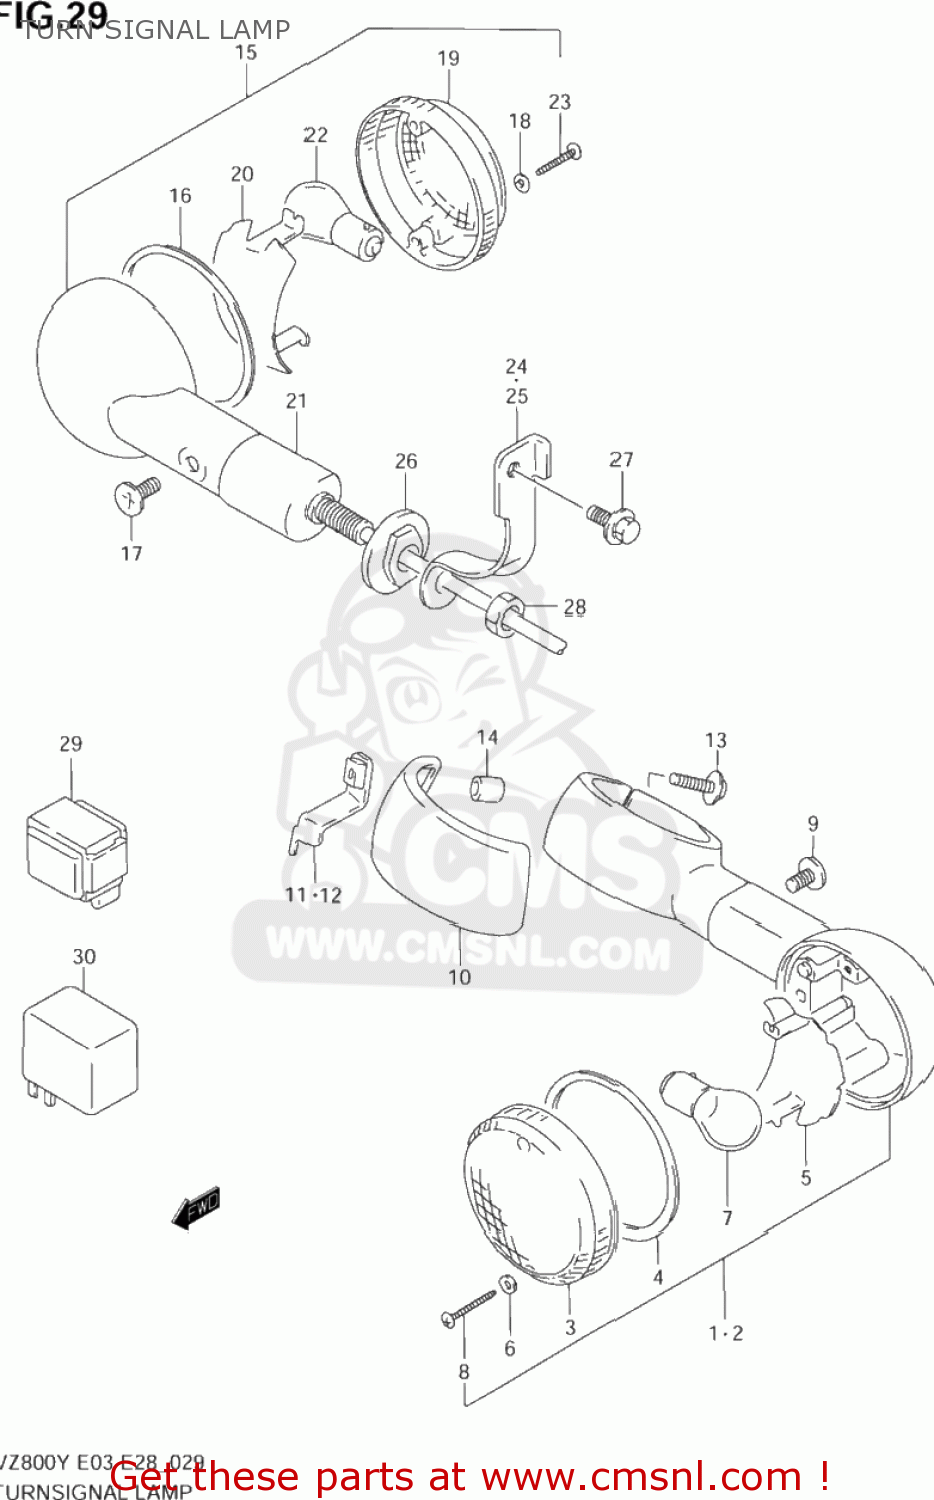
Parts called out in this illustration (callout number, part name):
1	LAMP ASSY,FR TURN SIGNAL,R
2	LAMP ASSY,FR TURN SIGNAL,L
3	LENS
4	GASKET (NAS)
5	REFLECTOR
6	GASKET (NAS)
7	BULB(12V21/5W)
8	SCREW
9	SCREW
10	COVER,FR TURNSIGNAL STAY
11	BRACKET,FR TURNSIGNAL,R
12	BRACKET,FR TURNSIGNAL,L
13	SCREW(6X25)
14	SPACER(6.4X9.2X12)
15	LAMP ASSY,RR TURNSIGNAL,R
16	GASKET (NAS)
17	SCREW
18	GASKET (NAS)
19	LENS
20	REFLECTOR
21	STAY,TURNSIGNAL RR
22	BULB(12V21W)
23	SCREW
24	REINF,RR TURNSIGNAL,R
25	REINF,RR TURNSIGNAL,L
26	SPACER,RR TURNSIGNAL
27	BOLT
28	NUT
29	RELAY ASSY
30	RELAY ASSY,TURNSIGNAL LAMP
